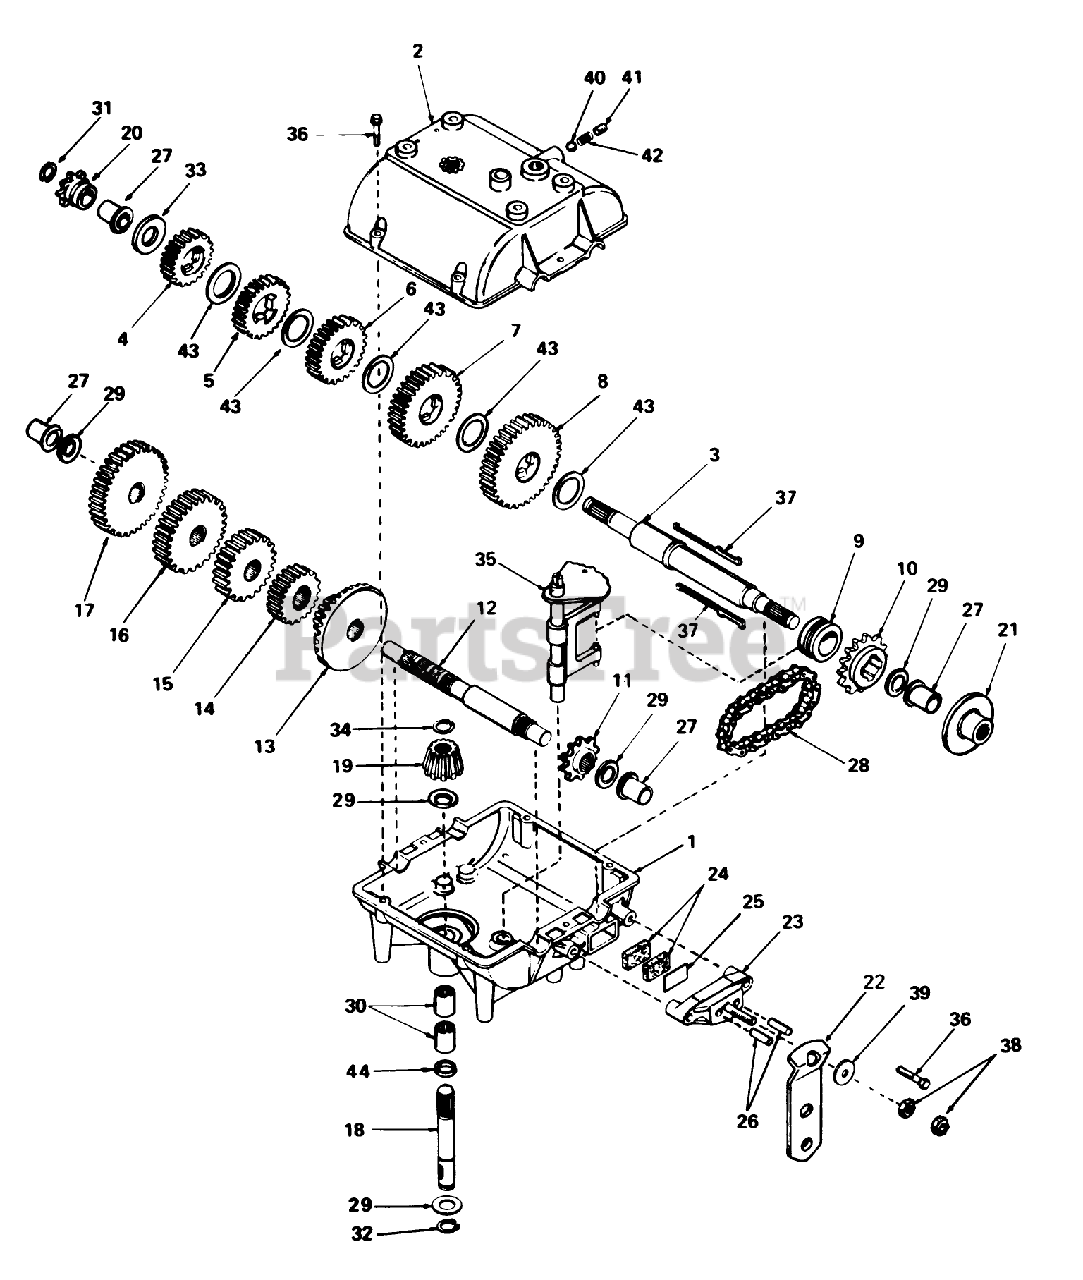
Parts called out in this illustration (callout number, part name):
1	Case-Transmission
2	Cover-Transmission
3	Shaft-Output Brake
4	Gear-Spur 20 teeth
5	Gear-Spur (22 teeth)
6	Gear-Spur, 25 Teeth
7	Gear-Spur, 30 Teeth
8	Gear-Spur, 35 Teeth
9	Collar-Shift
10	Sprocket-18 Teeth
11	Sprocket-9 Teeth
12	Countershaft
13	Gear-Bevel (42 tooth 15 tooth spur gear)
14	Gear-Spur, 20 Teeth
15	Gear-Spur, 25 Teeth
16	Gear-Spur (28 teeth)
17	Gear-Spur (30 teeth)
18	Shaft-Input
19	Bevel Pinion-Input
20	Sprocket (8 teeth)
22	Lever-Brake
23	Holder-Brake Pad
24	Brake Pad
25	Brake Pad Plate
26	Dowel Pin
27	Bushing-Flange
28	Chain-Roller #41
29	Washer
30	Bearing-Needle
31	Piston Asm (.020 O S)
32	Ring-Snap
33	Washer
34	Ring-Retainer
35	Rod and Fork ASM
36	Ring Set (.020 O S)
38	Locknut
39	Washer
40	Ball-Steel
41	Screw-Set
42	Spring
43	Washer
44	O Ring
